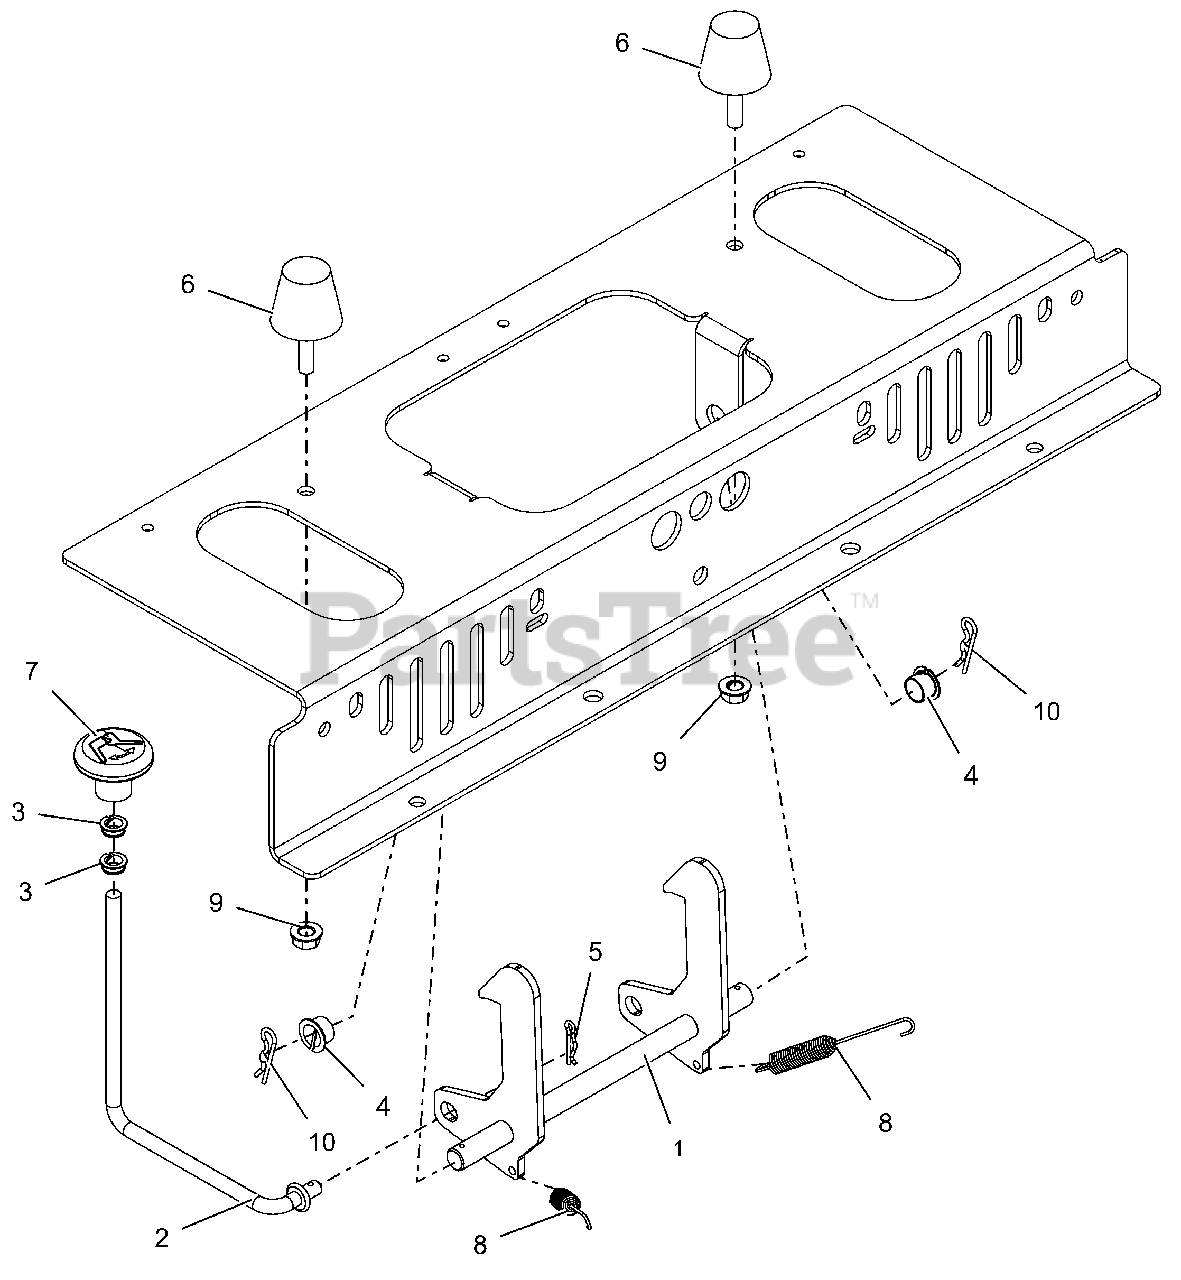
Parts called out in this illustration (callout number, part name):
1	SEAT LATCH WLDMT - LOW FILM
2	LINKAGE, SEAT RELEASE
3	BUSHING, POLYLINER-.38 SNAPIN
4	BUSHING, POLYLINER-.50 SPLIT
5	PIN-HAIR, ENDRIES #25 YWZC
6	BUMPER,STUD MOUNTED CONE SHAPE
7	KNOB, PUSH/PULL
8	SG-TENS .043X.44X3.31 WLD 5.8
9	@NUT-SPNLK-FLG .312-18 YWZC
10	PIN-HAIR INT .08X.38X1.42 YWZC
